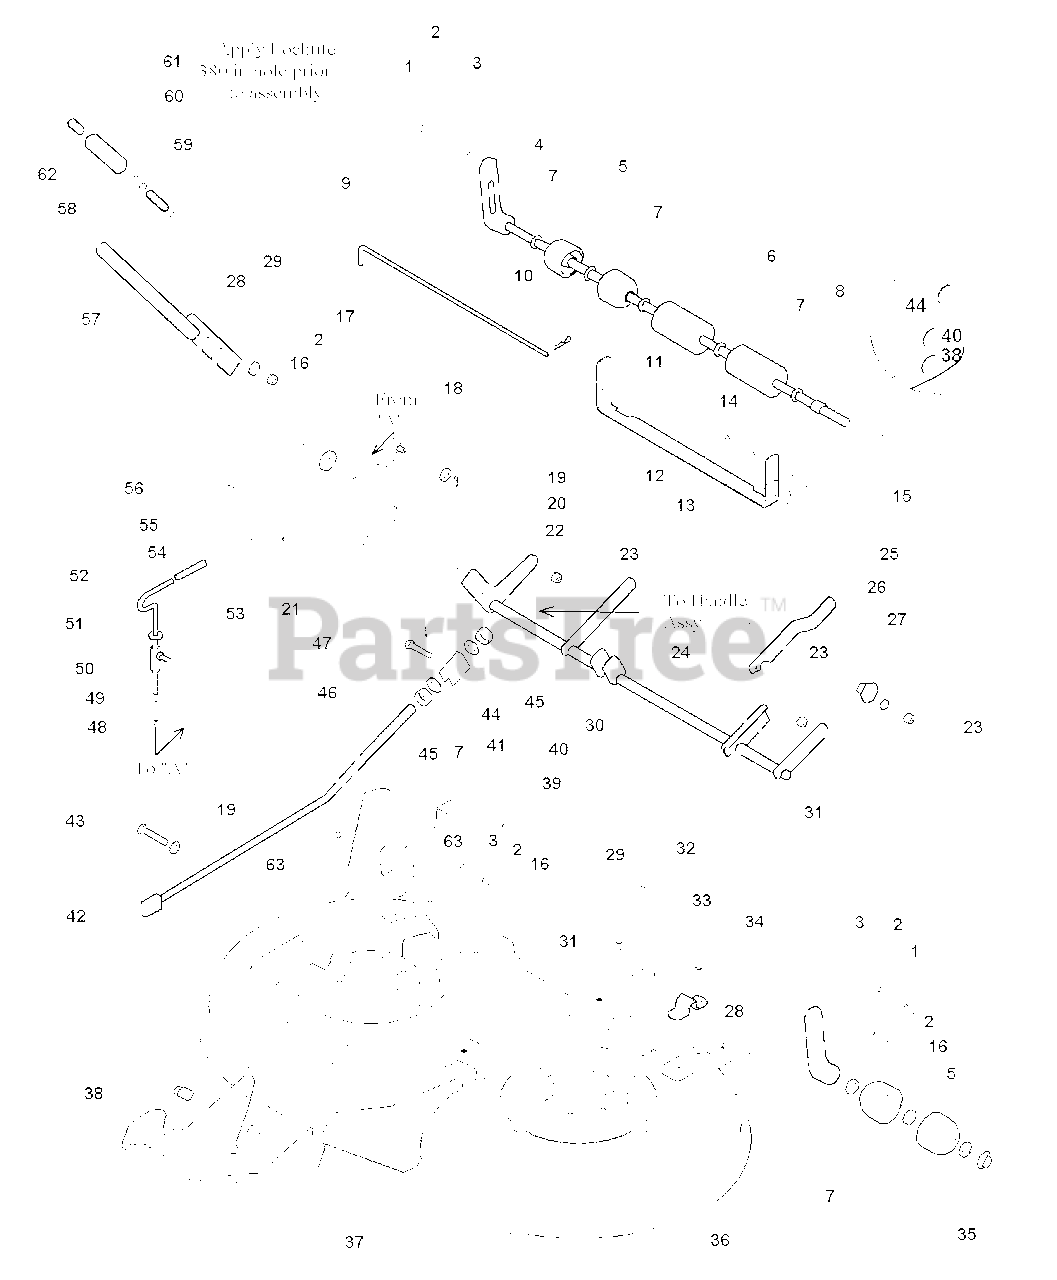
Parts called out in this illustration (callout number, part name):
1	CAPSCREW, Hex Head, 5/16-18 x 1
2	WASHER, 5/16
4	SHAFT & BAR ASSEMBLY, 40" Roller
7	WASHER, 5/8
9	ROD, Transport
10	CLIP, Hair Pin
11	U-BRACKET
12	NUT, Hex Centerlock 5/16-18
14	WASHER, 5/16
15	CAPSCREW, Hex Head, 5/16-18 x 1-1/4
16	CAPSCREW, Taptite Hex Washer Head, 5/16-18 x 1
18	PIVOT, 3/4 Hex
19	WASHER, 3/8
20	PIN, Cotter
21	BRACKET, Adjusting
22	CARRIAGE BOLT, 5/16-18 x 1
23	NUT, Hex Flange Lock, 5/16-18
24	CARRIAGE BOLT, 5/16-18 x 1-1/4
26	CAM, Eccentric 1 1/8 Hex
27	WASHER, 5/16
28	NUT, Hex Collar Lock, 5/16-18
29	FASTENER, Panel
30	SHAFT ASSEMBLY, Rocker
31	CAPSCREW, Hex Head, Taptite 5/16-18 x 7/8
33	CAPSCREW, Taptite Hex Washer Head, 5/16-18 x 3/4
34	STRAP, Roller Support
35	NUT, Push 5/8
36	BAR, Roller
37	NUT, Hex Aluminum Lock, 3/8-16
39	NUT, Hex Centerlock 3/8-16
40	BRACKET, Height of Cut
41	DECAL, Height of Cut
42	ROD, Adjustment
43	CAPSCREW, Hex Head, 3/8-16 x 1-3/4
44	TRUNNION, Rod
45	NUT, Hex, 5/8-11
46	PIN
47	CLIP, Hair Pin, 1/8 x 1
48	NUT, Hex Jam 3/8-16
49	NUT, Hex Flange, 3/8-16
50	GUIDE ASSEMBLY, Rod
51	ROD & WASHER ASSEMBLY, Adjust Handle
52	GRIP, Black Vinyl For Rod
53	NUT, Hex Lock Esna Light, 1/4-20
54	LATCH, 5/16 WIRE
55	CAPSCREW, Hex Head, 1/4-20 x 2-1/4
57	HANDLE ASSEMBLY, Lift
58	SPRING, Compression
59	WASHER, 5/16
60	GRIP, Black Soft for Rod
61	BUTTON, Black Nylon for Rod
62	PUSH NUT, 1/4
